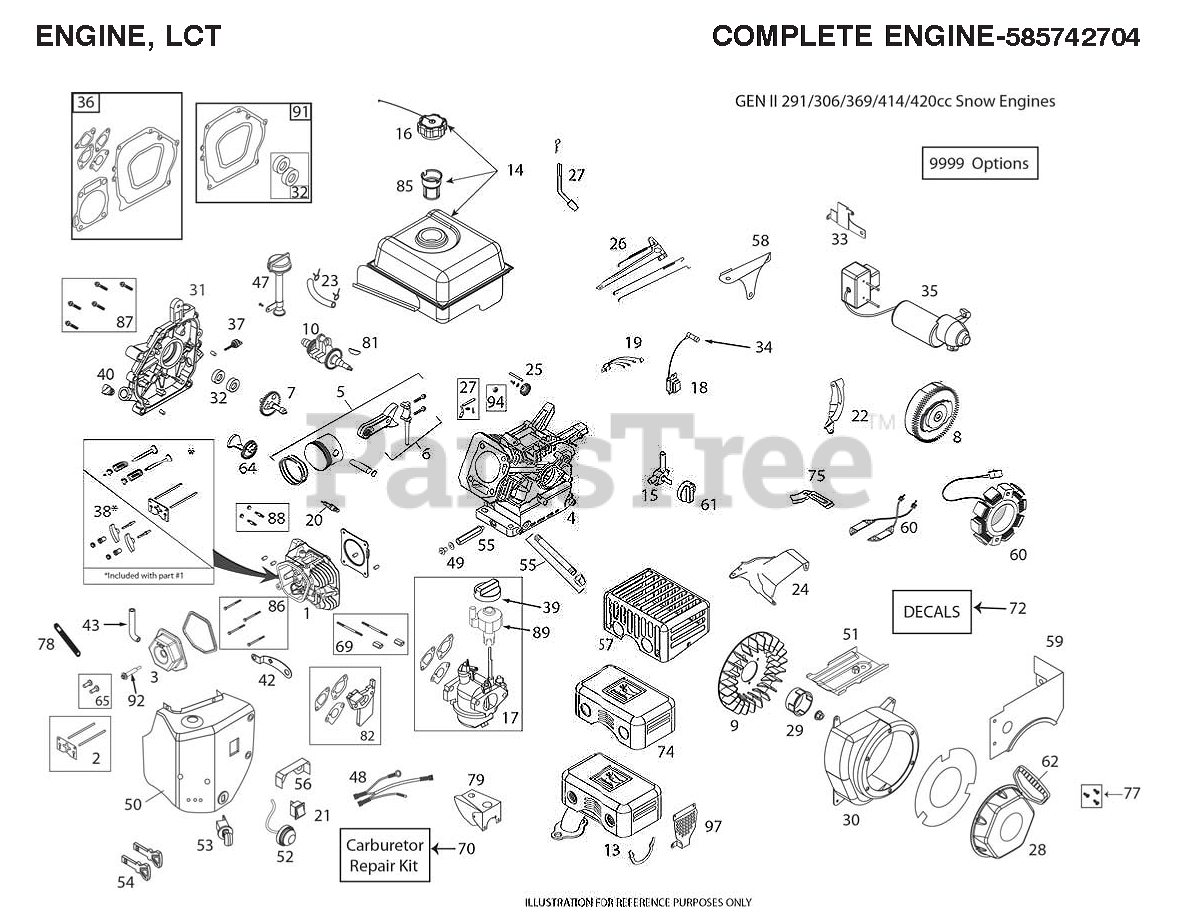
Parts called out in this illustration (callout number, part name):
1	CYLINDER HEAD LCT 178 INCLUDES
2	PUSH ROD TAPPET KIT
3	VALVE.COVER.LCT.414CC.
5	PISTON ROD ASM.LCT SK3691400.1
7	CAMSHAFT(SK4141600)
8	FLYWHEEL.EL.ST.SKSN4408.1
9	FLYWHEEL.FAN(SK4144000)
10	CRANKSHAFT KEYED #18 LCT 414C
13	MUFFLER ASSY LCT SNO
14	FUEL.TANK.ASSY.SNOW(SKSN4300)
15	FUEL.PETCOCK.SNOW(SKSN4900)
16	FUEL.TANK.CAP.SNOW(SKSN4301)
17	CARBURETTOR L18D LCT 369
18	IGNITION.COIL.(CDI).291-414CC
20	SPARK.PLUG(2083810)
21	ON/OFF.SWITCH.SNOW(SKSN4403)
23	FUEL HOSE KIT
24	CONTROL.SPEED.FIXED.LCT.SKSN44
25	GOVERNOR.GEAR.ASSY(SK4142900)
26	GOVERNOR.ARM.ASSY(SKSN4502)
27	GOVERNOR.SHAFT(SK4143100)
29	STARTER CUP
30	BLOWER LCT 414CC
31	CRANKCASE.COVER.LCT.414CC.HIGH
32	OIL SEAL KIT NON-GENERATOR
33	ELECTRIC.START.BRKT(SKSN4405)
34	SPARK.PLUG.BOOT.SNW,SKSN4691.1
35	STARTER EUROPEAN 230V ELECTRIC
36	GASKET KIT ENGINE LCT 369
37	DIPSTK.OIL.BLK.LCTSK4143711.1
38	ROCKER ARM KIT
39	CHOKE.KNOW.SNOW(SKSN4500)
40	NONREMVABLE.OIL.PLUG(SK4143715
43	BREATHER TUBE LCT 291/369/414
47	HIGHOIL.FILL.ASSY.KIT(SKSN4911
48	WIRE.HARNESS.SNOW
49	OIL.DRAIN.PLUG
50	HEATER.BOX.ASSY-SNW(SKSN4100)
51	SHIELD.CYLINDER.SNOW(SK4141010
52	PRIMER.BULB.ASSY(SKSN4304)
53	KEY.SWITCH.ASSY.SNOW(SKSN4401)
54	KEY SET(2 KEYS) SKSN0407.1
55	OIL PIPE DRAIN EXTENDED.LCT SK
56	SHIELD.VAPOR(SKSN4606)
57	CE COMPLIANT MUFFLER SHEILD
58	PLATE.GOVERN.LINK.S
59	FUEL TANK SKIRT.LCT.369/420CC
60	ALTERN.60WATT.SKSN2402.1
61	FUEL KNOB-SNOW
62	HANDLE.RECOIL.DELUXE.LCT
64	COUNTER WEIGHT KIT
65	TAPPET KIT.LCT.SK2911005.1
69	STUD.CARB.MOUTING.KIT.414CC
70	CARBURETTOR REPAIR KIT 291CC/4
72	ARIENS 414 SNOW DECAL KIT
74	MUFFLER SHIELD
75	SHIELD.U/FYWHL.CHARG(SKSN4604)
77	BOLT.KIT.RECOIL.LCT.ALL.ENGINE
78	STRAP.RETAINING.TUBE.BREATHER.
79	SHIELD CARBURRETOR COVER 414
81	KEYS.FLYWHEEL.208/414CC.5PACK
82	SPACER.CARBURETOR.414CC.LCT
85	STRAINER.FUEL.TANK.LCT.208CC
86	KIT.BOLT.CYLINDER.HEAD.(4PC)
87	KIT.BOLT.CRANKCASE.COVER.414CC
88	STUD.MUFFLER.KIT.LCT
89	KNOB LCT.SKSN5325.1 SPEED
91	GASKET KIT CRANKSHAFT.LCT
92	CENTER VALVE COVER BOLT
94	SEAL GOVERNOR SHAFT OIL.LCT
97	GUARD.EXHAUST
9999	HIGH ALTITUDE JET 6000FT
9999	KIT.BOLT.LCT.SK9990.1
